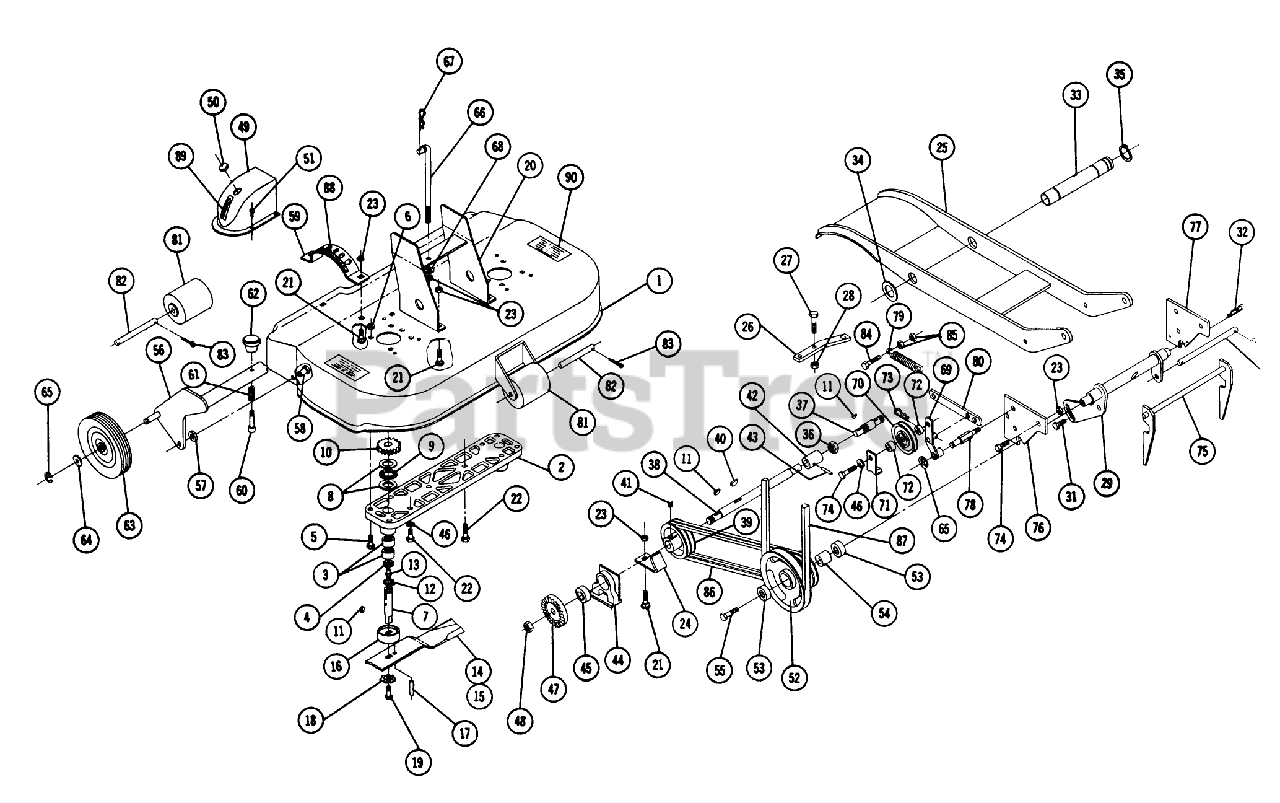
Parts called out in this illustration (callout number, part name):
5	Bolt 5/16-18 x 11/4
6	Nut 5/16-18
9	WASHER-THRUST
14	SVC BULLT 99A
15	SVC BULLT 99A
17	SPIROL ROLL PIN
19	Bolt 3/8-16 x 7/8
21	Bolt-3/8-16 x 3/4
22	Bolt 3/8-16 x 1
23	3/8-16 E.S.
26	Bracket Spring
27	Bolt 5/16-18 x
28	Nut-Nylok
31	Bolt Whizlock 3/8-16 x 5/8
32	Hairpin
34	Washer
35	SNAP RING
36	Nut Hex Jam 3/4-20
41	Set Screw
42	Coupling
46	Lockwasher
48	Nut Hex 5/8-18 Thin
50	PLUG BUTTON
51	SCREW
53	BALL BEARING
54	Spacer
55	Bolt Hex 7/16-14 x 3
57	WASHER
63	WHEEL ASSY
64	SHIM-WASHER
67	Hairpin
68	Washer
74	Bolt 3/8-16 x 1
76	PLATE R H
78	Support Idler
79	SPRING *R
80	Link
83	Cotter Pin
84	Bolt, 3/8-16 x 1/2
86	V-BELTS - MATCHED PR
89	Decal
